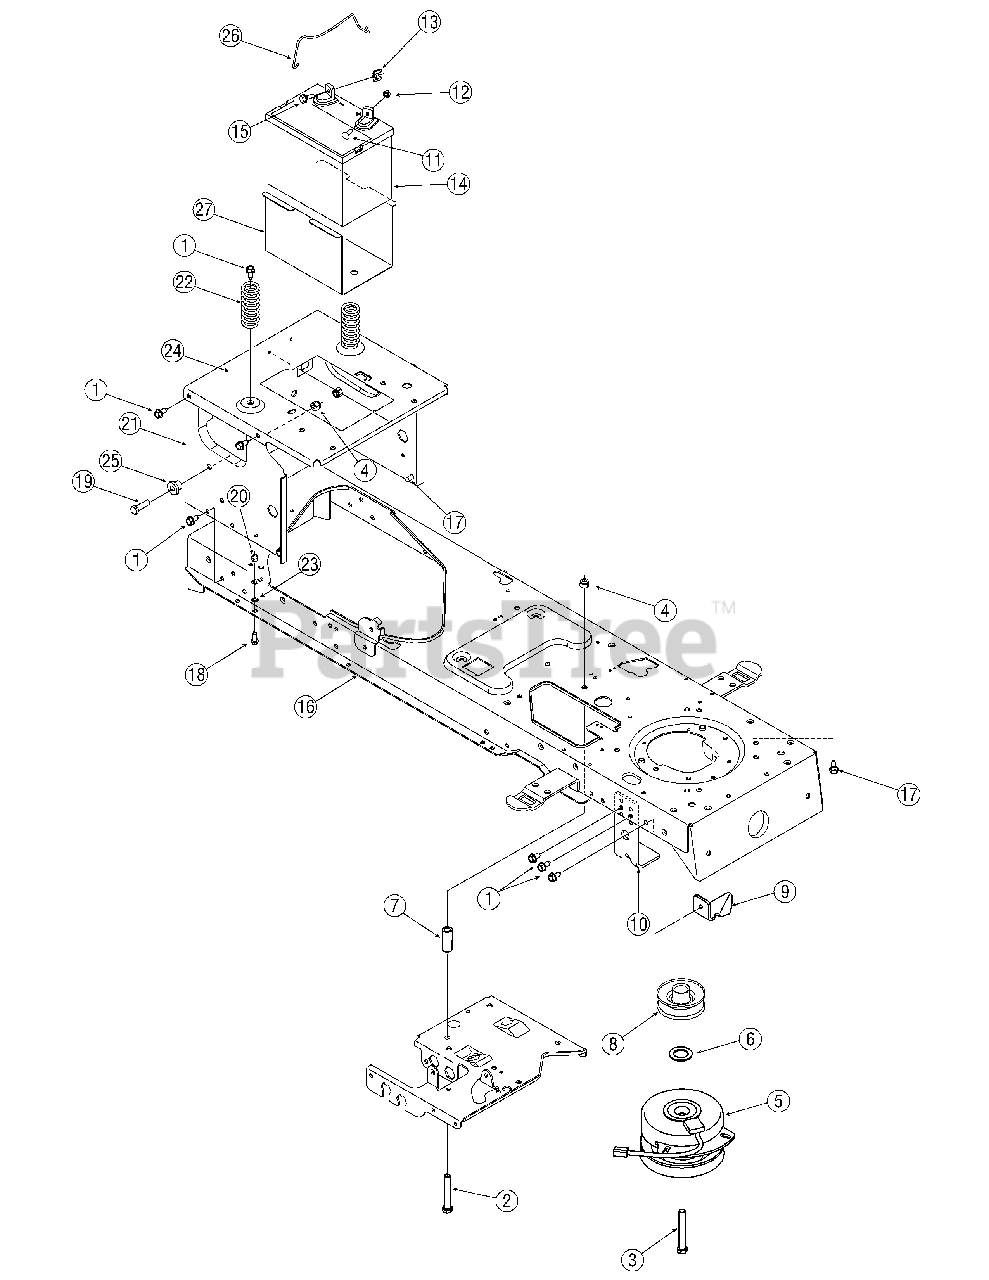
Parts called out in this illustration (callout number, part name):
1	Screw, 5/16-12, 0.75
2	Screw, 3/8-16, 2.50, Gr5
3	Screw, 7/16-20, 3.25, Gr5, Lock
4	Nut, Flange Lock, 3/8-16, GrF, Nylon
5	PTO Clutch, Electric
6	Washer, Flat, 1.031 x 1.620 x.095
7	Spacer,.385 ID x.635 OD x 1.54
8	Pulley, Engine, Electric PTO
11	Screw, Carriage, 1/4-20,.75, Gr5
12	Nut, Sems, 1/4-20
13	Nut, Wing, 1/4-20
14	Battery, 235 CCA
15	Screw, Shoulder,.250 x.150, 1/4-20
18	Screw, 1/4-20, 0.750
19	Screw, 3/8-16, 1.25, Gr5
20	Nut, Flange Lock, 1/4-20, GrF, Nylon
22	Spring, Compression, 1.28 OD x 3.125
23	Washer, Lock, 1/4, External
26	Hold Rod, Battery
